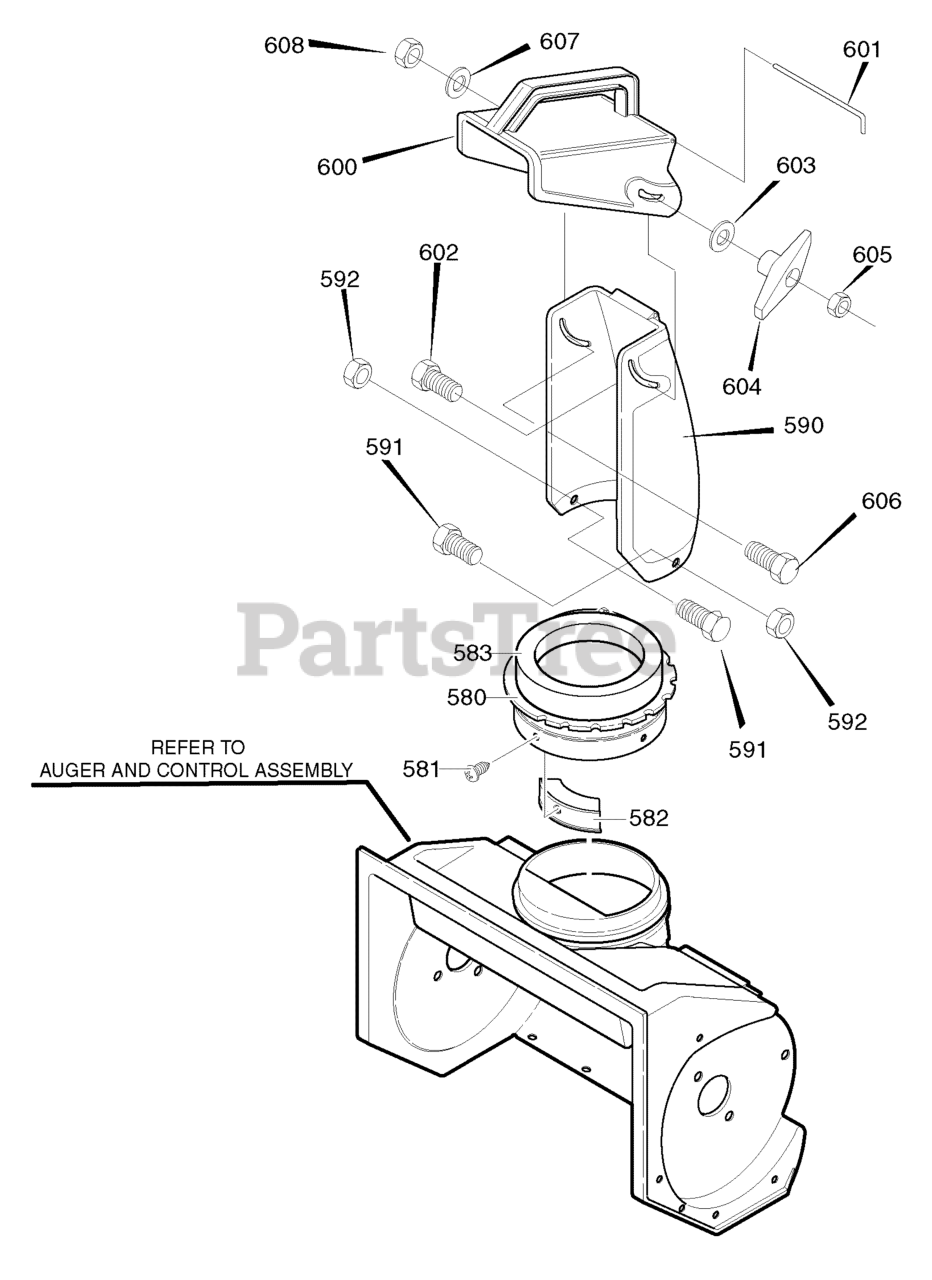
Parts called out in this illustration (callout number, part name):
580	RING, CHUTE
581	SCREW, #10 X .50
582	GUIDE, CHUTE
583	DONUT FOAM
590	CHUTE, DEFLECTOR LOWER
591	SCREW 1/4-20 X .50
592	NUT, 1/4-20
600	CHUTE DELFECTOR, UPPER
601	WIRE, CHUTE HINGE
602	BOLT, 5/16-18 X 1.25 CARRIAGE
603	WASHER, FLAT .349 X .69 X .066
604	KNOB, WING
605	NUT, 5/16-18
606	SCREW, 5/16-18 x 0.75
607	WASHER, FLAT .349 X .69 X .066
608	NUT, 5/16-18 HEX CONTROL LOCK
